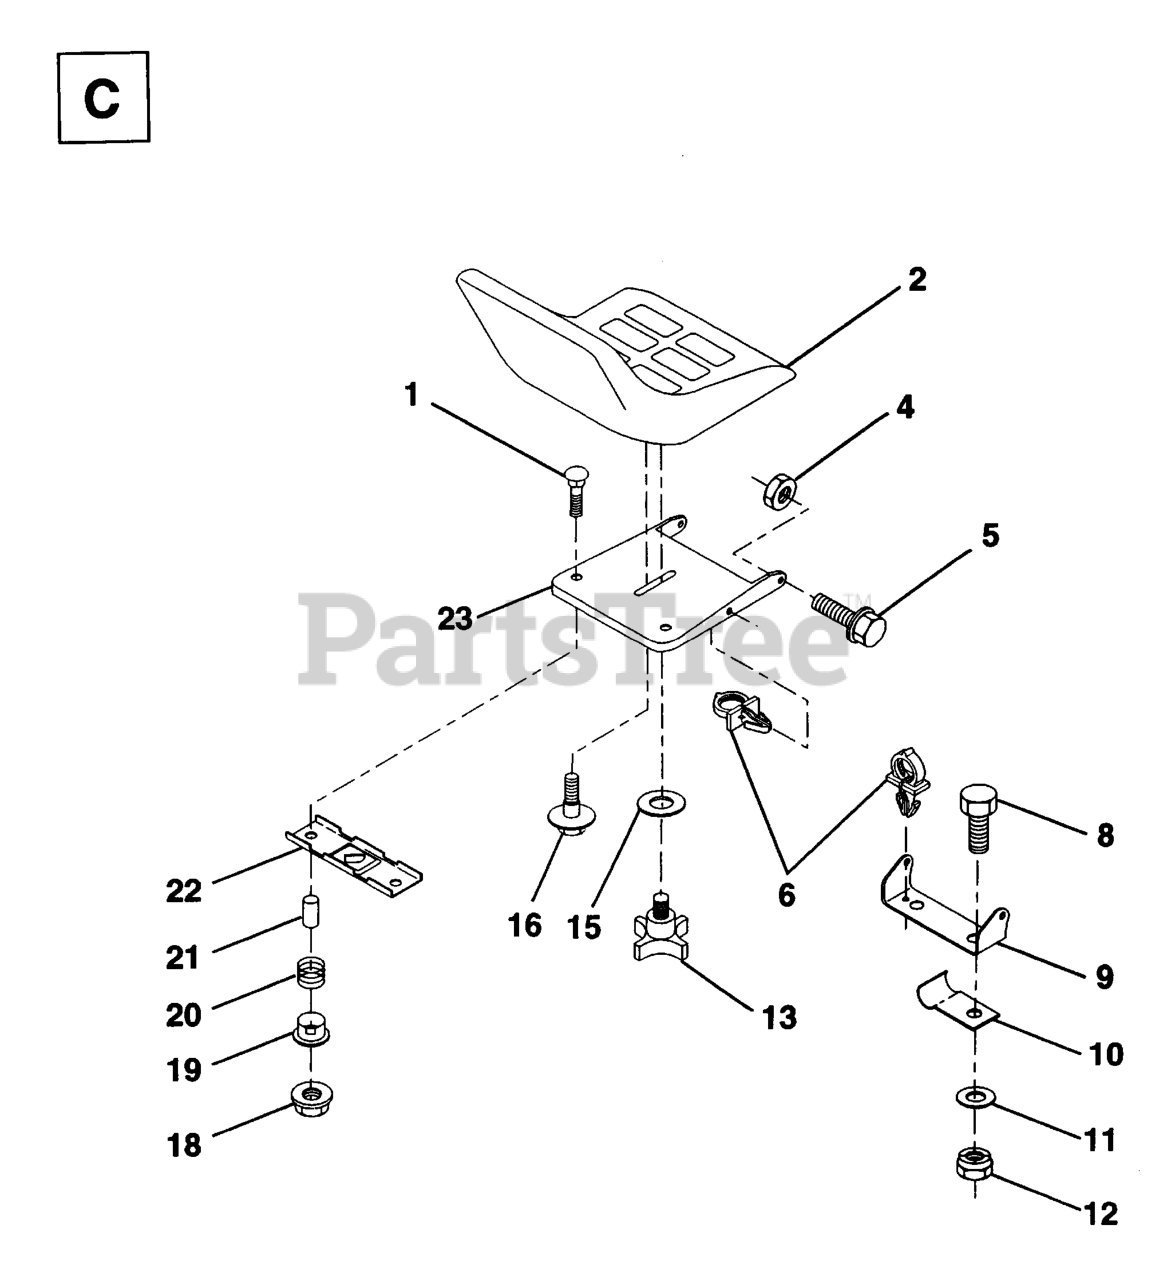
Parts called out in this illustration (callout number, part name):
1	Bolt Rdhd. Sht. Nk 1/4-20 x 1-3/8
2	SEAT
4	LOCKNUT
5	BOLT, SHOULDER LT
6	INSULATED CLIP
9	SEAT PIVOT BRKT
10	CLIP,INSULATOR
11	WASHER
13	KNOB 1/2" YT
16	BOLT,SHOULD
18	NUT T
21	SPACER SPLIT 28X.96
22	BRKT SWITCH
23	SEAT PAN
